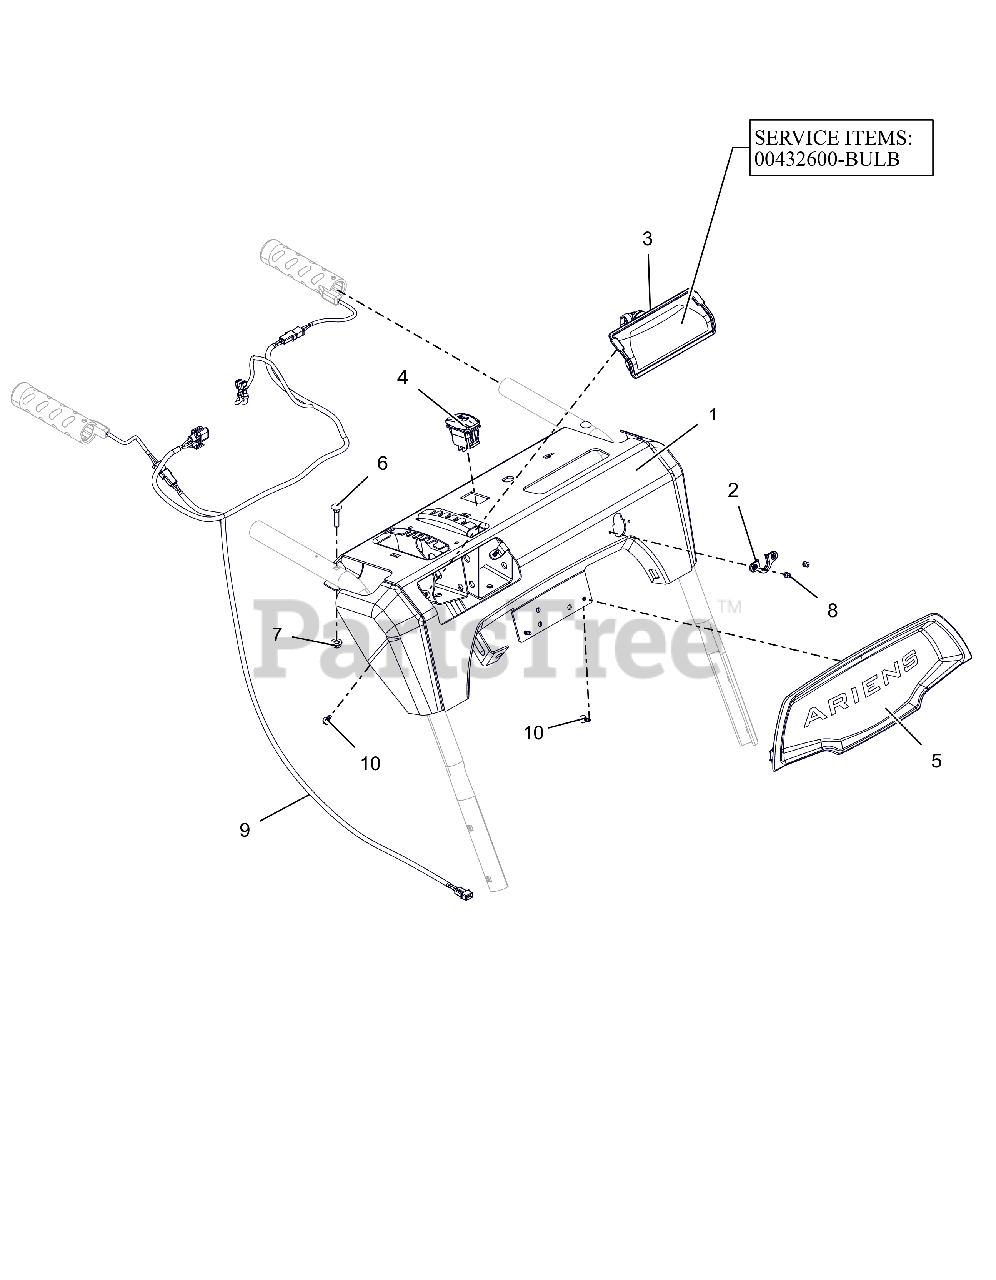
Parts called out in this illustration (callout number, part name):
1	CONTROL PANEL W/DECAL FRIC-QT
2	GROMMET, CABLE, QUICK TURN 2
3	HEADLIGHT ASY, HALO 20W 2SHOT
3	BULB, LIGHT-HALOGEN 20W
4	SWITCH,ROCKER SPST-ON/OFF
5	BEZEL, DASH - ARIENS LG DASH
6	BLT-RDHDXLSQNK.25-20X1.25 G5ZC
7	@NUT-LK-CTR-FLG .25-20 YWZC
8	RVT-POP #43 .125X.313 STL ZINC
9	HARNESS, LIGHT & WARMER
10	SCR-TAP #10X.50 BOSS INDHXHD
